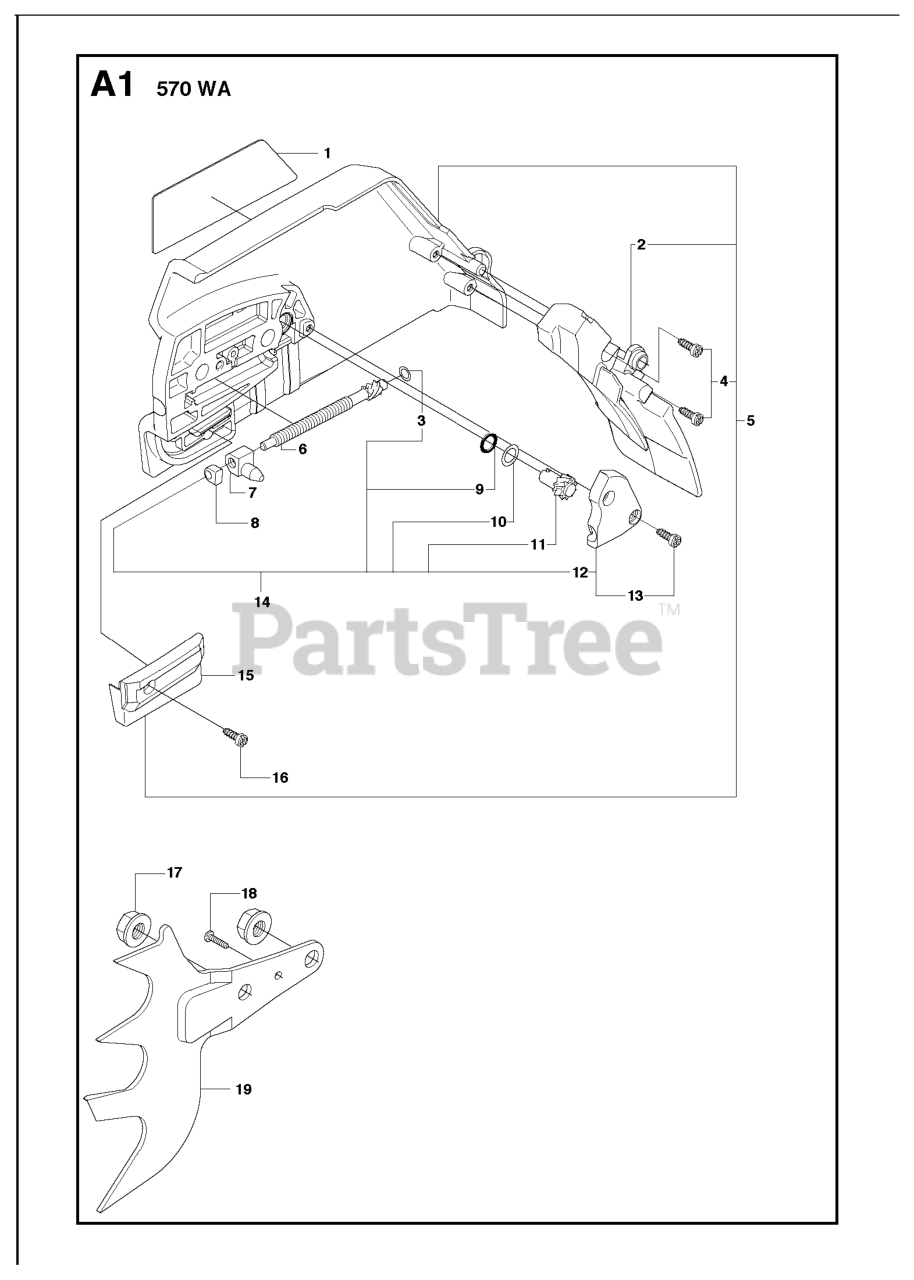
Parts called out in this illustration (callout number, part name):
5	CLUTCH COVER ASSY
6	WORM SCREW / ADJUSTER
11	WORM WHEEL
14	KIT-CHAIN TENSIONER
15	CHAIN GUIDE
17	NUT M8 FLANGE
19	FELLING DOG
